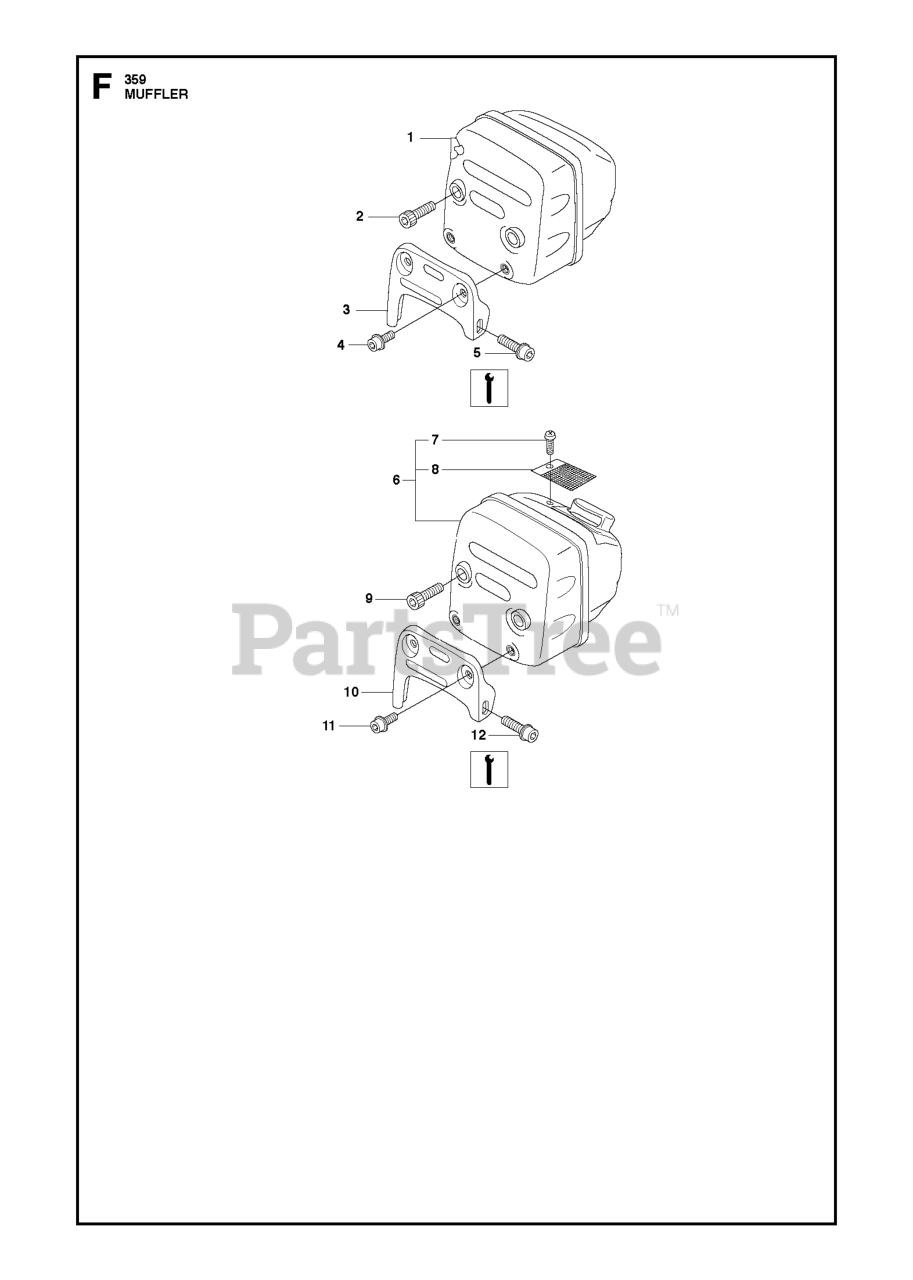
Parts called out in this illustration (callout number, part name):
1	MUFFLER ASSY
2	SCREW MC6S 6X16
4	SCREW M5 X 10
6	MUFFLER ASSY
6	MUFFLER CAT
8	SPARK ARRESTOR SCREEN
9	SCREW MC6S 6X16
11	SCREW M5 X 10
